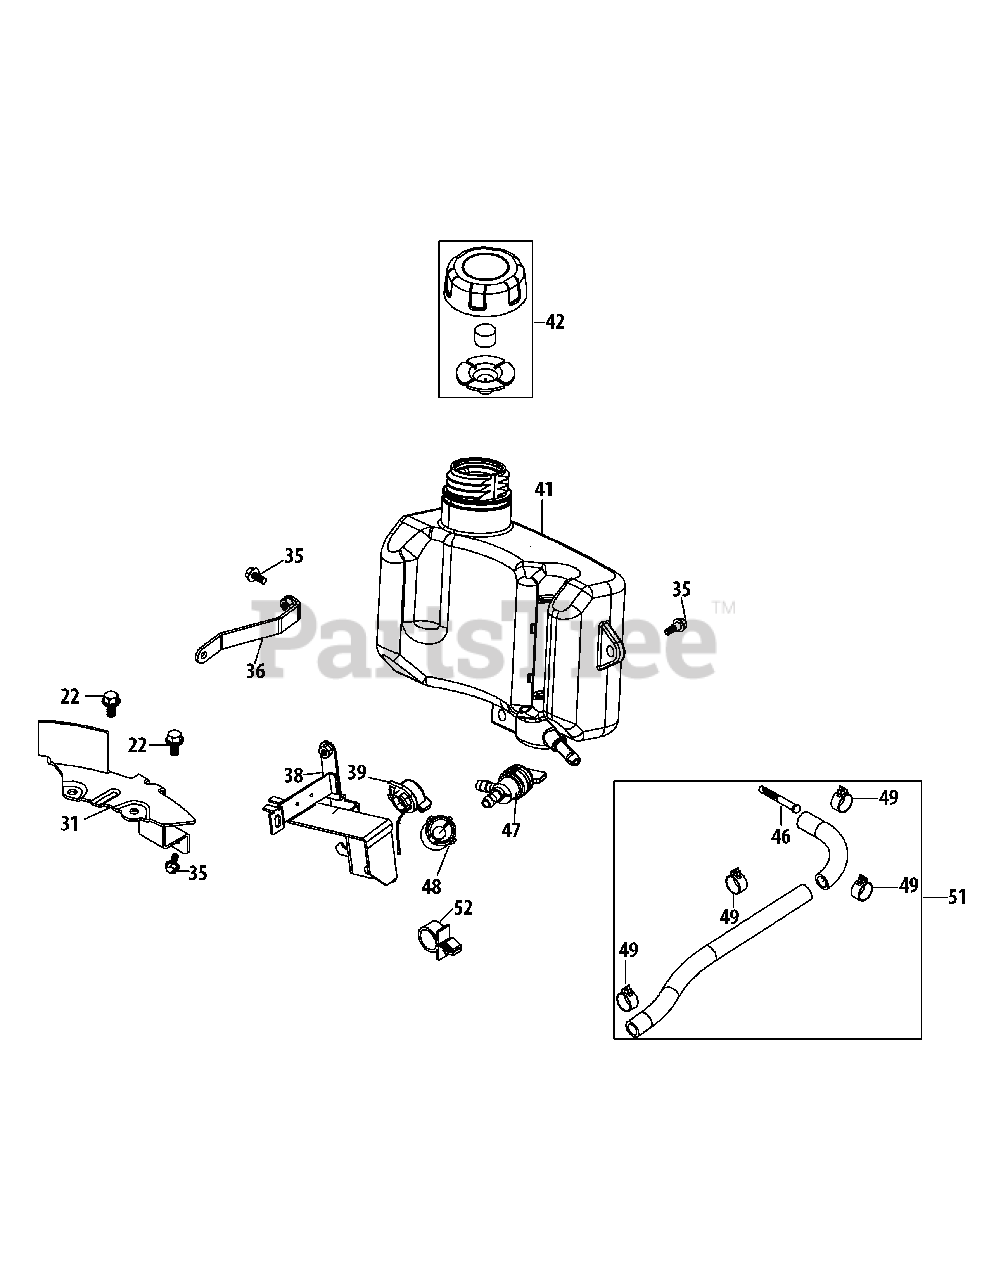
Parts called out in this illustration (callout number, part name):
22	Bolt M6×14
31	Fuel Tank Bottom Bracket
35	Fuel Tank Bolt
36	Fuel Tanksupport Bracket
38	Control/Tank Bracket
39	Ignition Key Switch
41	Fuel Tank - Clear White
42	Fuel Cap Assembly
46	Fuel Filter
47	Fuel Shut Off Valve
48	Fuel Shut Off Support Clip
49	Fuel Hose Clamp
51	Fuel Line Kit
52	Plastic Support Clamp
